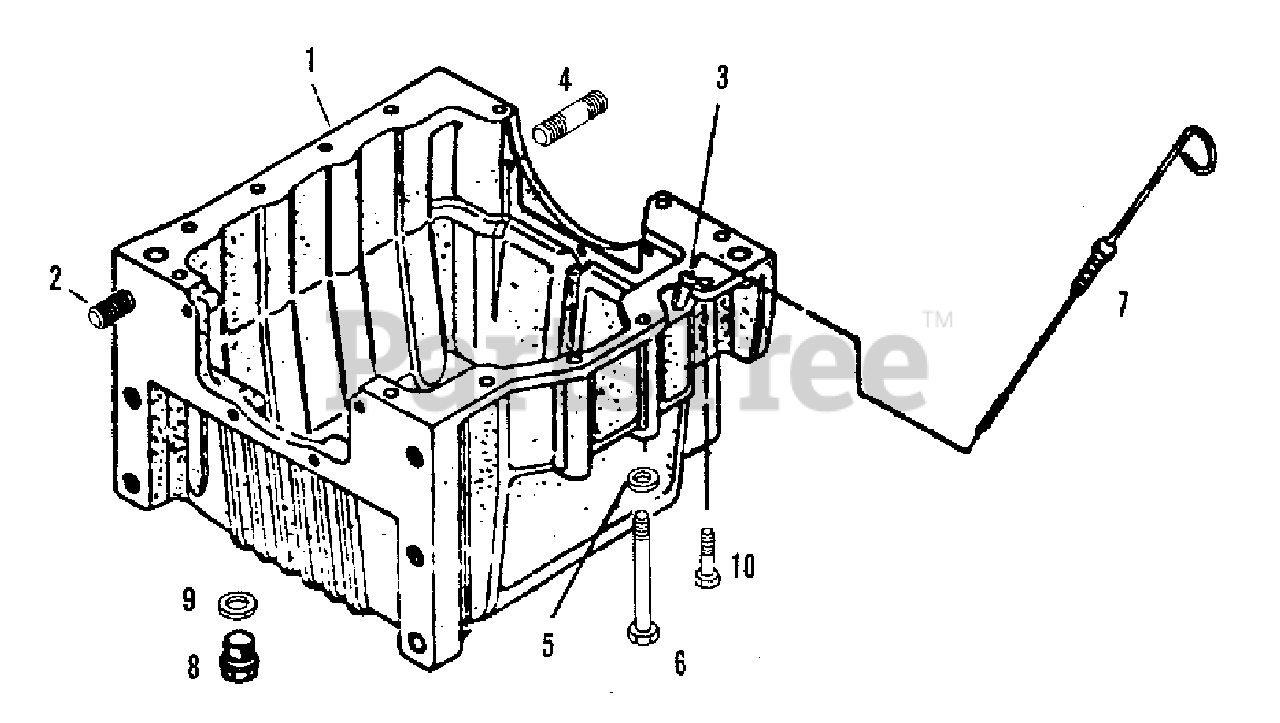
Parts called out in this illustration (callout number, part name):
1	CRANKCASE ASSEMBLY (Incl. Items 2 thru 4)
2	STUD, M14 x 51
3	ADAPTER, oil gauge
4	STUD, M8 x 36 oil seal cover
5	LOCKWASHER
6	CAPSCREW, M8 x 100
7	GAUGE, oil level
8	PLUG, magnet
10	CAPSCREW, M8 x 30
